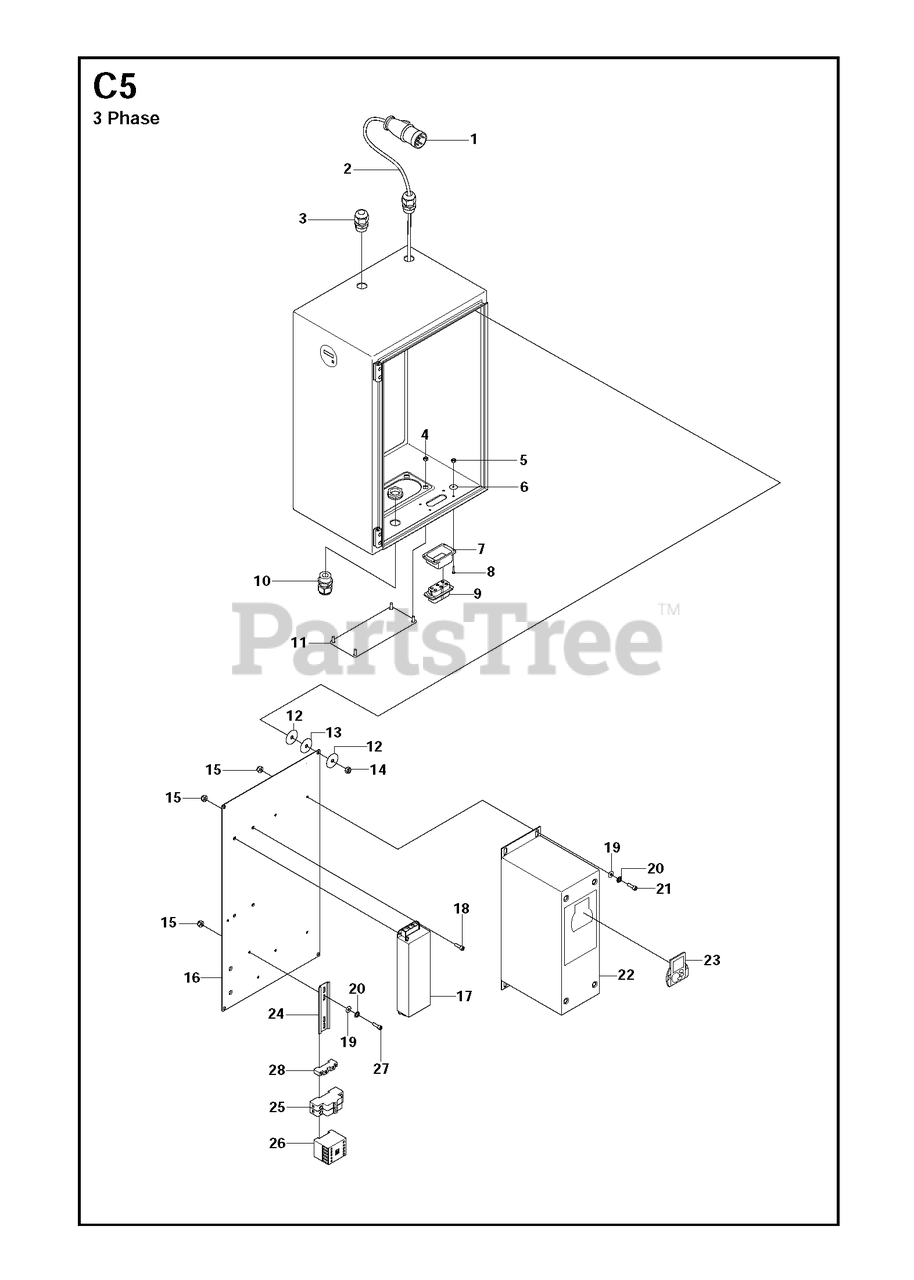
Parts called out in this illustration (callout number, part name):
4	HEXAGON LOCKING NUT
5	HEXAGON LOCKING NUT
14	HEXAGON LOCKING NUT
21	SCREW IHSCM
